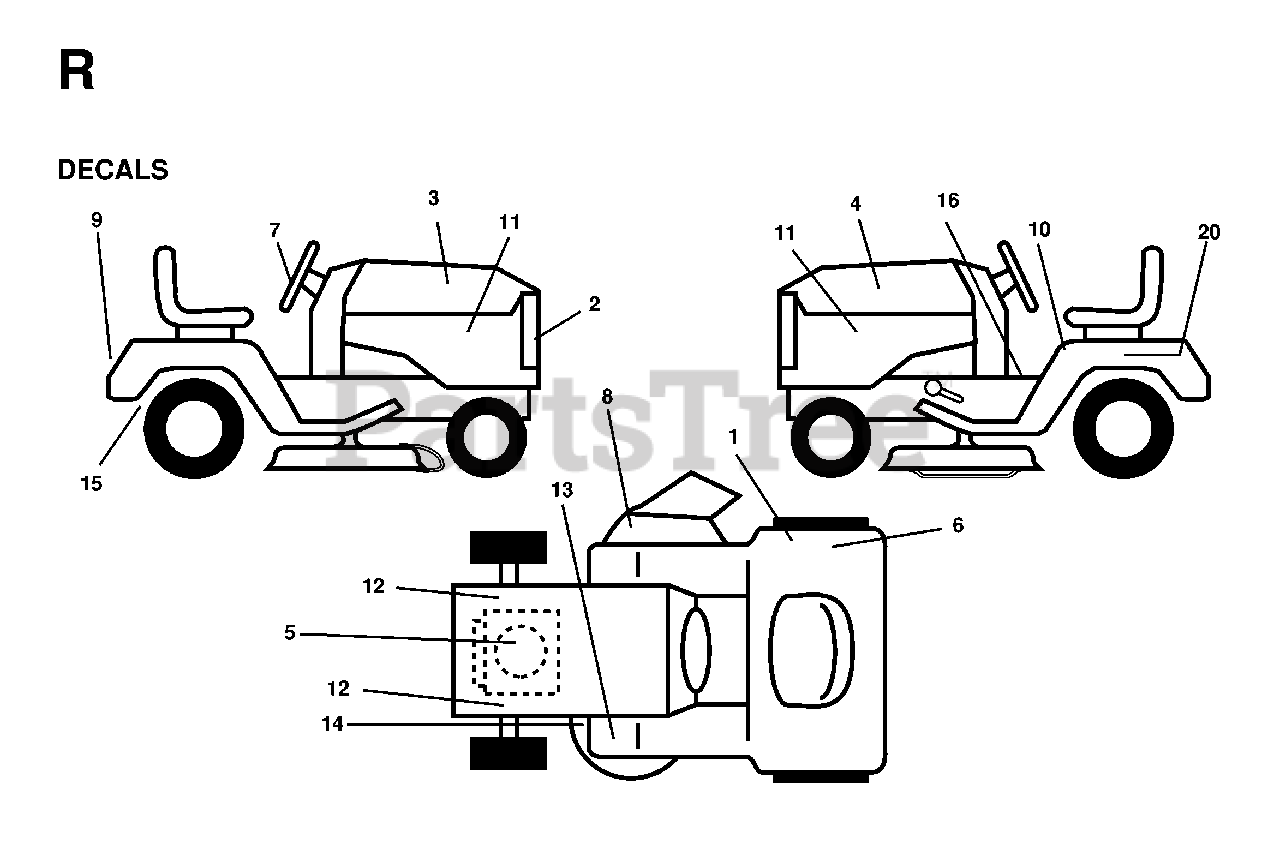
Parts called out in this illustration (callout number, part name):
1	DECAL CERTIFICATION
5	DECAL HP ENGINE
6	DECAL EUROPE STANDARD CE
8	DECAL MOWER CUT/FINGER
10	DECAL READ OWNER'S MAN SYMS
14	DECAL V BELT SCHEMATIC
16	DECAL PARK BRAKE
20	DECAL BTRY SYMBOLS
